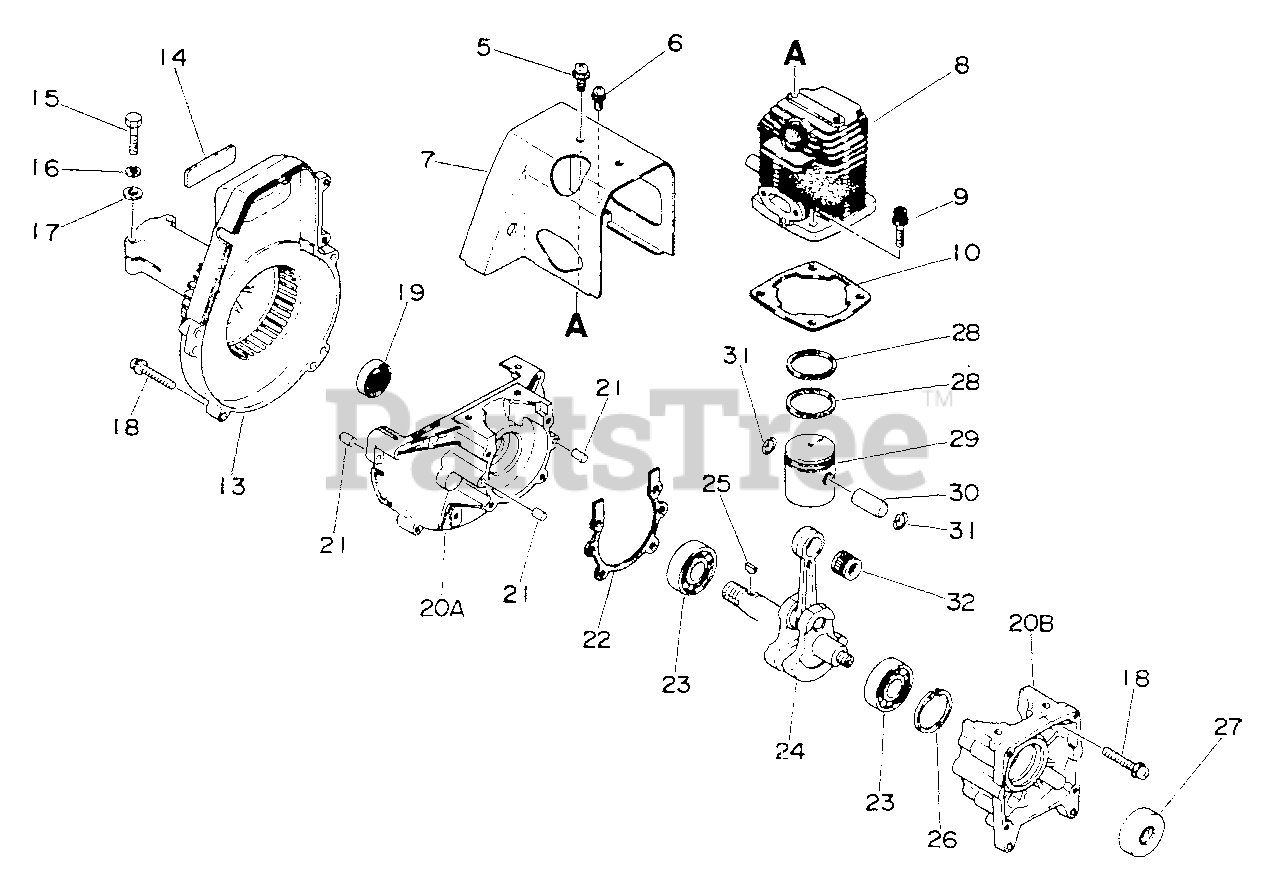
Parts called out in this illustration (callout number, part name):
5	SCREW - 5X10
6	SCREW - 4X10
7	COVER, ENGINE
8	CYLINDER
9	SCREW - 5X20
10	GASKET, CYLINDER
13	CASE, FAN
14	LABEL - MODEL 400AE
15	BOLT - 5X25
16	LOCKWASHER - 5
17	WASHER - 5
18	SCREW - 5X30
19	SEAL, OIL
20	CRANKCASE KIT
20A	CRANKCASE KIT
20B	CRANKCASE KIT
21	PIN - LOCATING
22	GASKET, CRANKCASE
23	BEARING, BALL - 6202
24	CRANKSHAFT ASSY
26	RING, RETAINING - 35
27	SEAL, OIL
28	RING, PISTON
29	PISTON
30	PIN, PISTON
31	RING, RETAINING - 8
32	BEARING, NEEDLE
